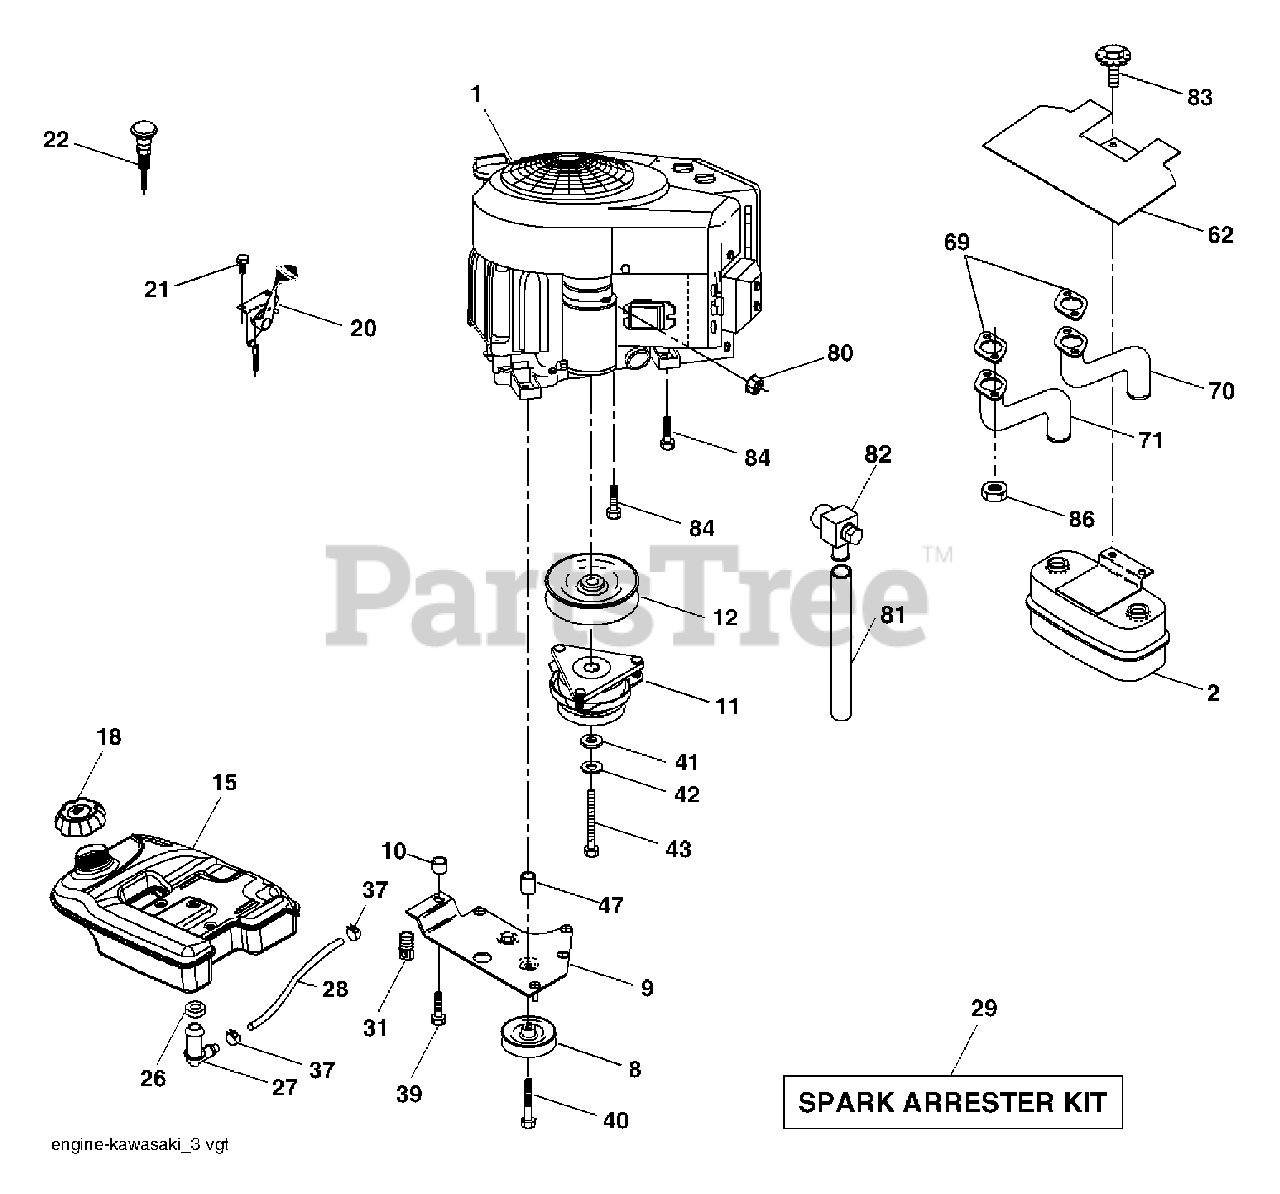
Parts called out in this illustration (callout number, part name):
1	Engine Kawa, Model No. FH641 V
2	Muffler Side
8	Pulley V-Idler
9	Keeper Asm. Belt Engine VGT
11	Clutch Electric
12	Pulley Engine VGT Elect Clutch
15	Tank Fuel Rear 5.0
18	Cap Fuel
20	Control Throttle
21	Screw 10 x 314 Single Lead Hex
22	Control Choke
26	Bushing
27	Stem Tank Fuel
28	Fuel Line
29	Spark Arrester Kit
31	Clip Push-In Hinged
37	Clamp Hose
39	Screw TT 3/8-16 x 2-1/4 unc
40	Screw TT 3/8-16 x 4 unc
41	Washer 1-1/2 OD X 15/32 I D X .250
42	Washer Lock 7/16
43	Bolt Hex 7/16-20 x 3.75 Or. 5
62	Shield Heat Muffler
70	Tube Exhaust LH
71	Tube Exhaust RH
80	Nut Flange M8-1.25
81	Oil Drain Tube
82	Valve Drain Oil
83	Bolt 5/16-18 unc x 1-3/4 W/Sems
84	Screw 3/8-16 x 1-1/2
86	Nut Hex Flange Toplock M8-1.25
